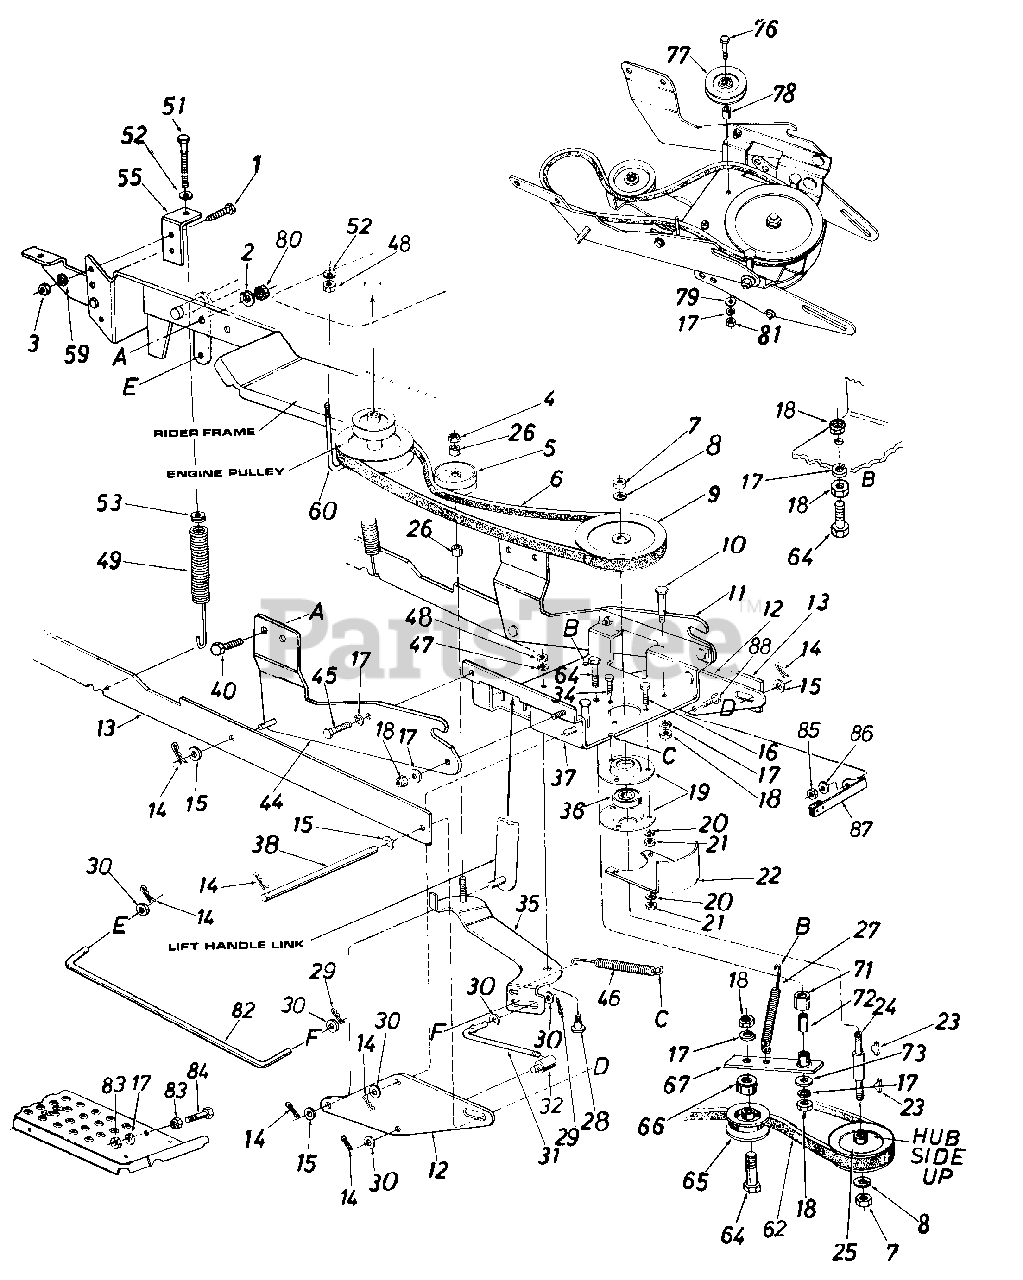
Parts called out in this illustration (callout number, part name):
1	Hex Bolt 1/4-28 x 1.0" Lg. Grade 5
2	L-Wash. 114" I.D.
3	Hex Nut 1/4-28 Thd.
4	Hex Cent. L-Nut 3/8-16 Thd.
5	Idler Pulley
6	"V"-Belt
7	Hex Jam Nut 5/8-11 Thd.
8	L-Wash. 5/8" I.D.*
9	5/8 Pulley x 6.5" O.D.
10	Shoulder Bolt
11	Channel Support Brkt. R.H.
12	Linkage Brkt.
13	Linkage Arm Ass'y.
14	Intern. Cotter Pin .50" Dia.
15	Fl-Wash.
16	Hex Bolt 5/16-18 x 1.25" Lg.
17	L-Wash. 3/8" I.D.
18	Hex Jam Nut 3/8-16 Thd.
19	Bearing Housing
20	L-Wash. 5/16" I.D.*
21	Hex Nut 5/16-18 Thd.
24	Pulley Spindle
25	5/8 Pulley 6.28" I.D. x 5.56" O.D.
26	Spacer .383" I.D. x .503" O.D. x .562" Lg.
27	Extension Spring .54" O.D. x 5.25"
28	Shoulder Bolt
29	Cotter Pin 3/32" Dia.
30	Fl-Wash.
31	Control Rod
32	Ferrule
34	Hex Sems Bolt 5/16-18 x .75" Lg.*
35	Clutch Idler Brkt. Ass'y.
36	Ball Bearing
37	Channel Ass'y.
38	Lift Handle Shaft
40	Hex Self-Tap Scr. 1/4-20 x .75" Lg.
44	Channel Supporting Brkt. L.H.
45	Hex Bolt 3/8-16 x 1" Lg.
46	Extension Spring
47	L-Wash. 5/16" I.D.
48	Hex Nut 5/16-18 Thd.
49	Helper Spring
51	Hex Bolt 5/16-18 x 2.0" Lg. Special
52	Bell-Wash. .345" I.D. x .88" O.D. x .06"
53	Spring Insert
60	J-Bolt 5/16-18 Thd.
62	"V"-Belt
64	Hex Bolt 3/8-16 x 2" Lg.
65	Idler Pulley
66	Spacer .385" I.D. x .503" O.D. x .562" Lg.
67	Idler Arm Ass'y.
71	Spacer.38" I.D.
72	Spacer .3775" I.D. x .6" O.D. x 8.3" Lg.
73	Fl-Wash. 3/8" I.D. x 1" O.D. x 1.27"
76	Hex Bolt 3/8-16 x 2.5" Lg. (Grade 5)
77	Idler Pulley .38" I.D. x 3.06" O.D.
78	Spacer .385" I.D. x .63" O.D. x.76" Lg.
79	Fl-Wash. .39" I.D. x 1-314" O.D. x 3/16"
80	Hex L-Nut 1/4-20 Thd.
81	Hex Nut 3/8-16 Thd.
82	Clutch Control Rod
83	Hex Nut 3/8-24 Thd.
84	Hex Bolt 3/8-24 x 2.25" Lg.
85	Hex Nut 3/8-16 Thd.
86	Bell-Wash. 3/8" I.D.
87	N Auger Brake Brkt. Ass'y.
88	Hex Bolt 3/8-16 x 5/8" Lg.
